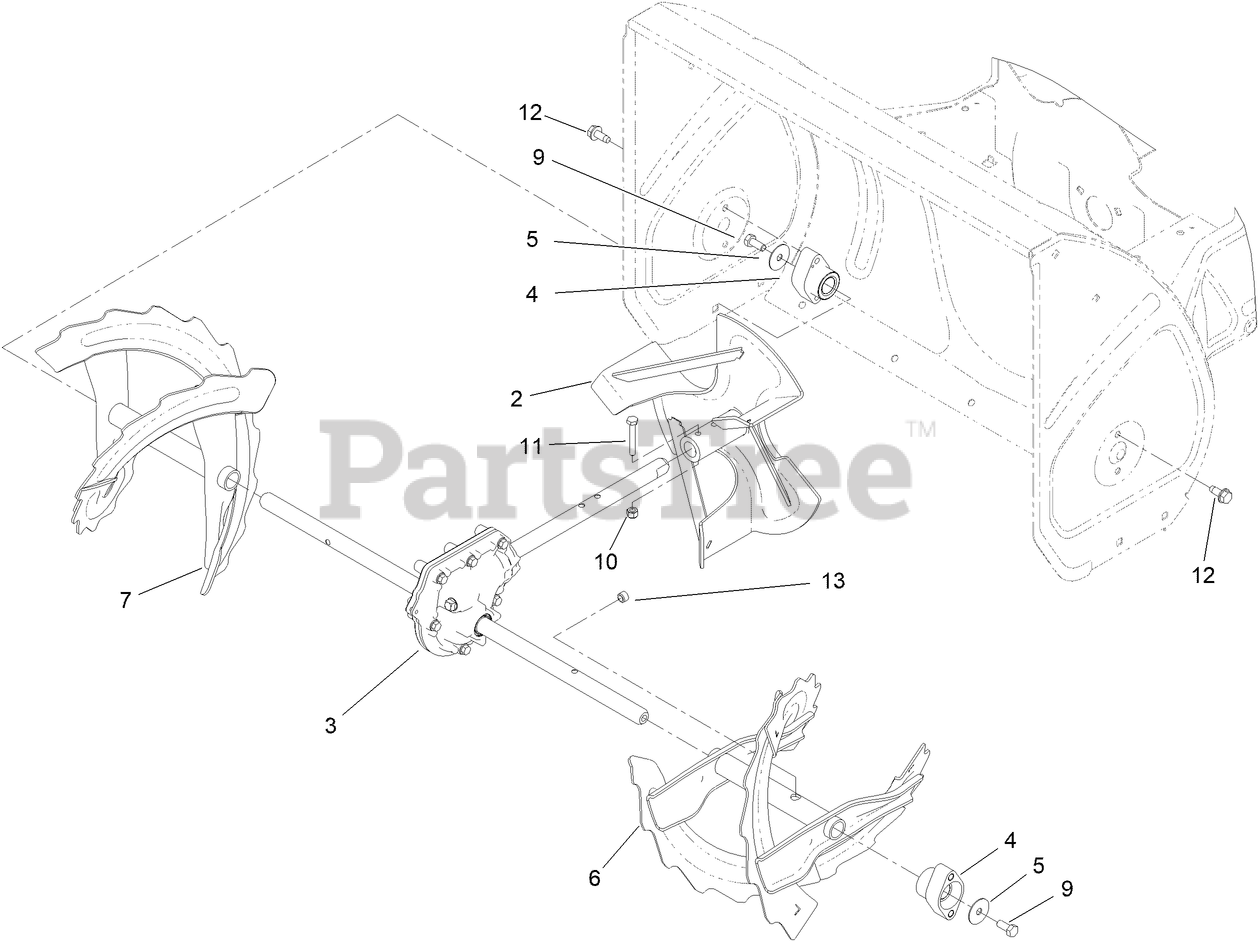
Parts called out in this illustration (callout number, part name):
2	IMPELLER ASM
3	GEARCASE ASM
4	BEARING-AUGER
5	WASHER-THRUST
6	AUGER ASM, LH (WELDMENT)
7	AUGER ASM, RH (WELDMENT)
9	SCREW-HH
10	NUT-LOCK, NI
11	SCREW-HH
12	SCREW-HWHTF
13	SPACER-BLADE, ROTOR
